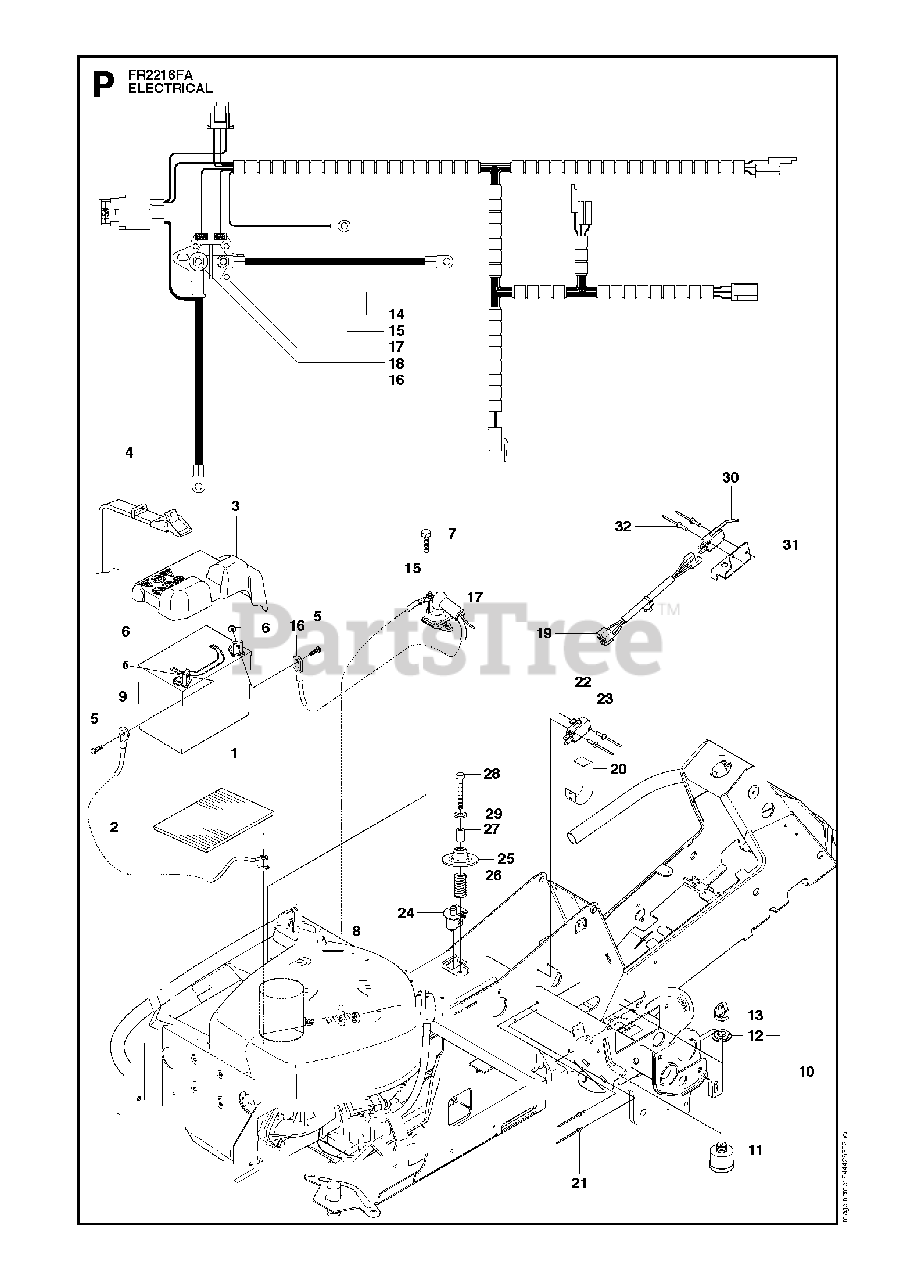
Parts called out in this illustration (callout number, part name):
5	SCREW EHHM
10	IGNITION SWITCH
11	IGNITION SWITCH
12	NUT
13	IGNITION KEY
19	WIRING
27	SPACER TUBE
28	SCREW
29	WASHER BRB 8.4X17
30	MICRO SWITCH
